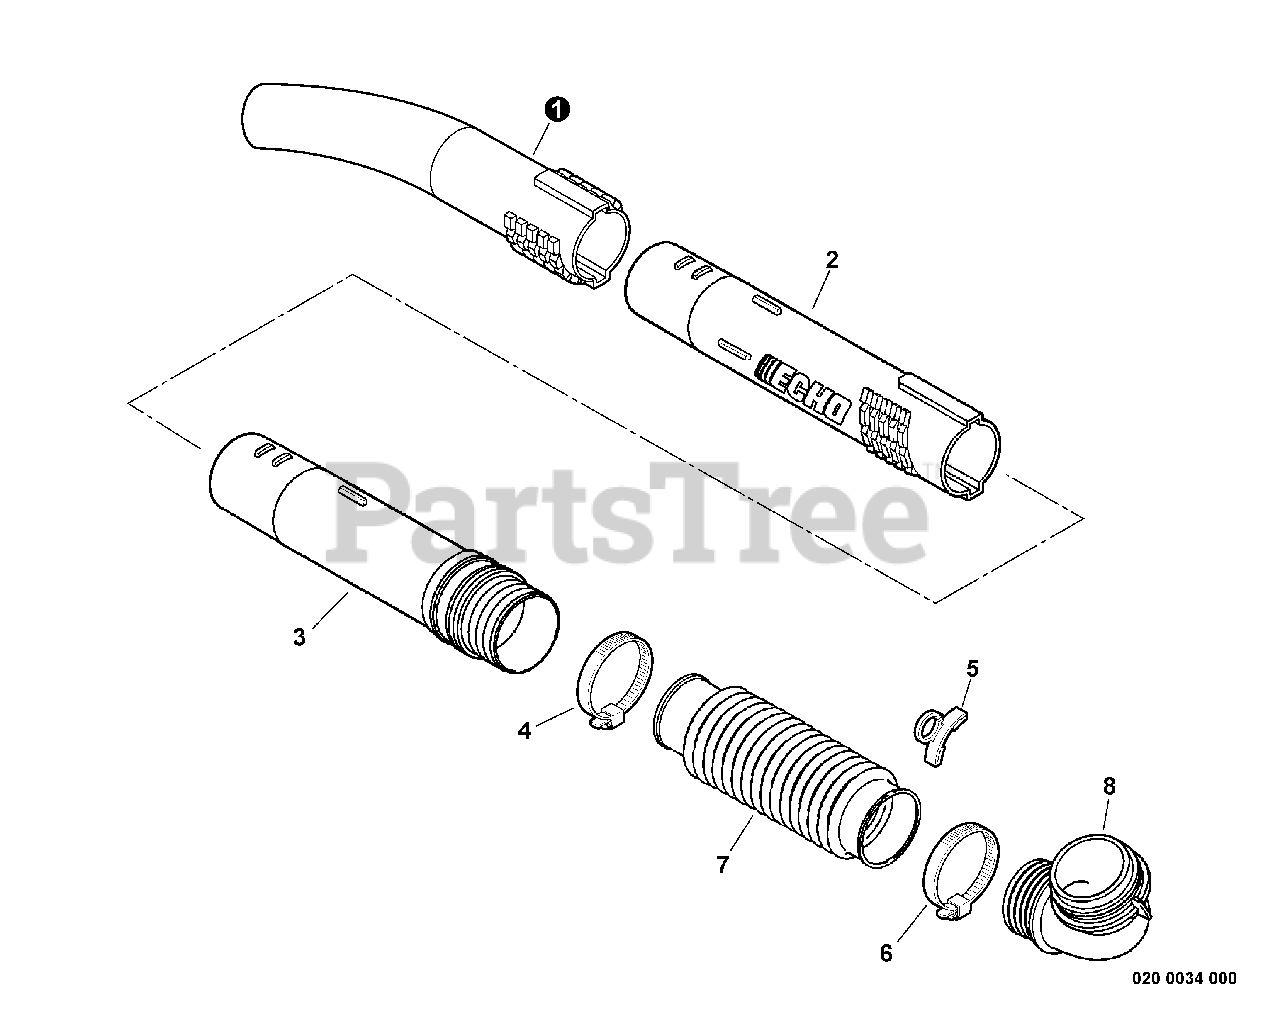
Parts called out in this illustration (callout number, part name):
1	TUBE, BLOWER - CURVED
2	TUBE, BLOWER - STRAIGHT
3	TUBE, BLOWER - SWIVEL
4	CLAMP 58.7 MM / 82.5 MM
5	CLIP, CABLE
6	CLAMP - BAND
7	TUBE, BLOWER - FLEXIBLE
8	TUBE, BLOWER - ELBOW
